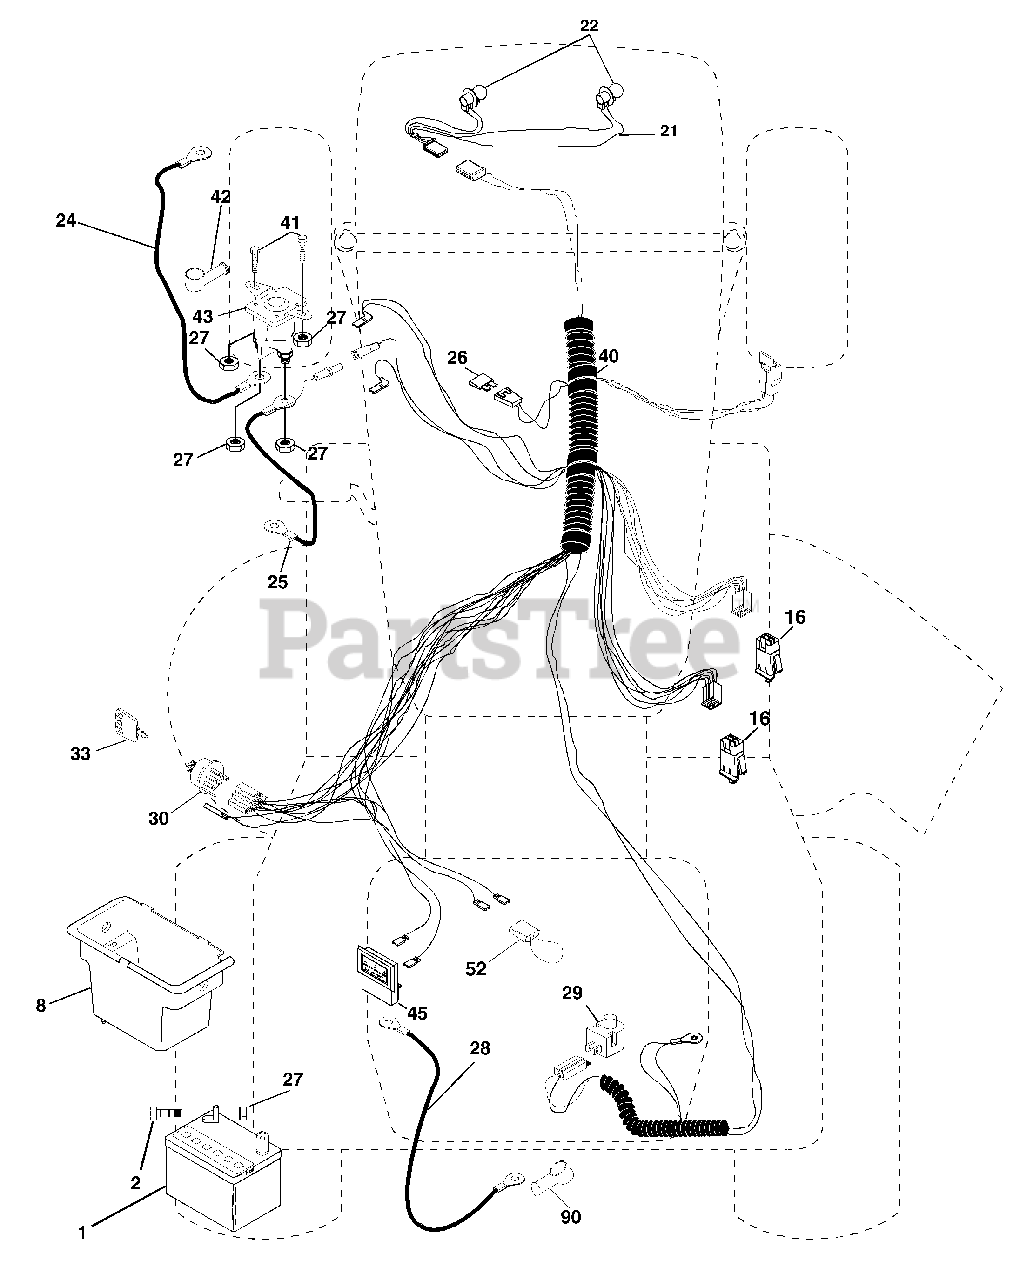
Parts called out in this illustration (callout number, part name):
1	Battery
2	Bolt Hex Hd 1/4-20unc X 3/4
8	Box Battery Fender
16	Switch Interlock
21	Harness Socket Light with 415J
22	Bulb, Light # 1156
24	Cable Battery
25	Cable Battery 6 Ga Red w/16 wire
26	Fuse 20 Amp
27	Nut Keps Hex 1/4-20 Unc
28	Cable Ground 6ga 12 black
29	Switch Plunger Nc Gray
30	Switch Ign
33	Key Ign Molded Generic
40	Harness Ign
41	Bolt Fin Hex 1/4-20unc x 1/2
42	Cover Terminal Red
43	Solenoid
45	Ammeter Rectangular
52	Protection Loop
90	Cover Terminal Battery
